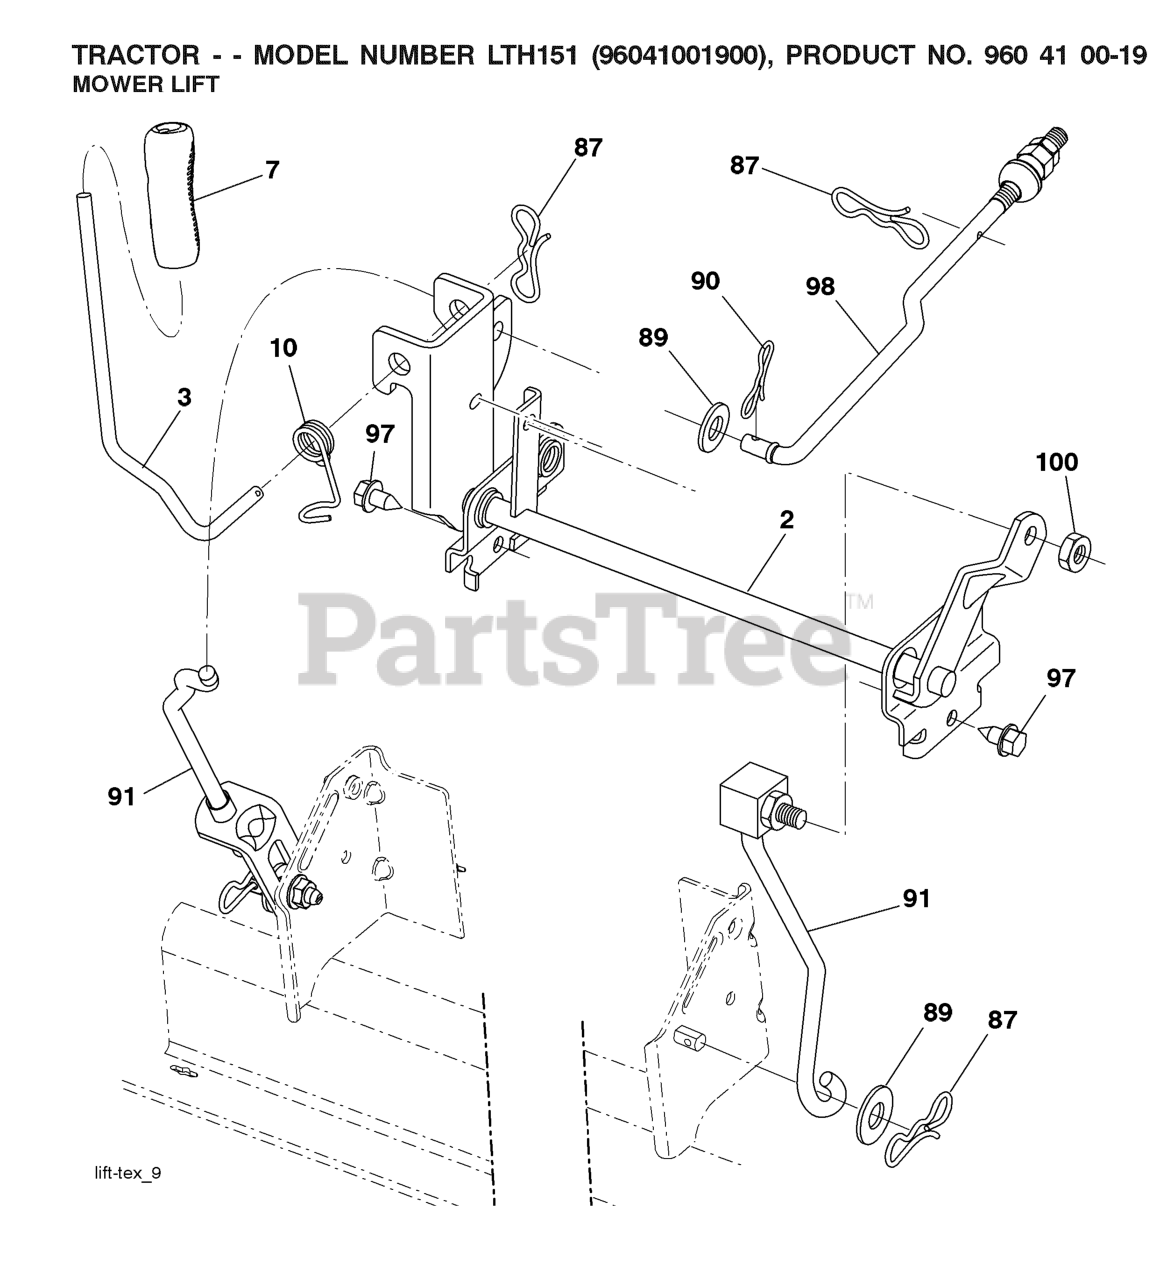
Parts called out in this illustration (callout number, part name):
2	SHAFT.ASM.LIFT.CROSS.H
3	LEVER.LIFT.HANDLE.LT
7	GRIP.HANDLE.LIFT.PVC.BLACK
10	SPRING.TORSION.LIFT.HANDLE
87	PIN.COTTER.7/16.BOW TI.
89	WASHER.CLEAR.ZINC
90	PIN.COTTER.5/16.BOW TI
91	LINK.ASM.LIFT.REAR
97	SCREW 3/8-16X3/4
98	LINK LIFT SUSP. FRONT MOWER
100	NUT **
